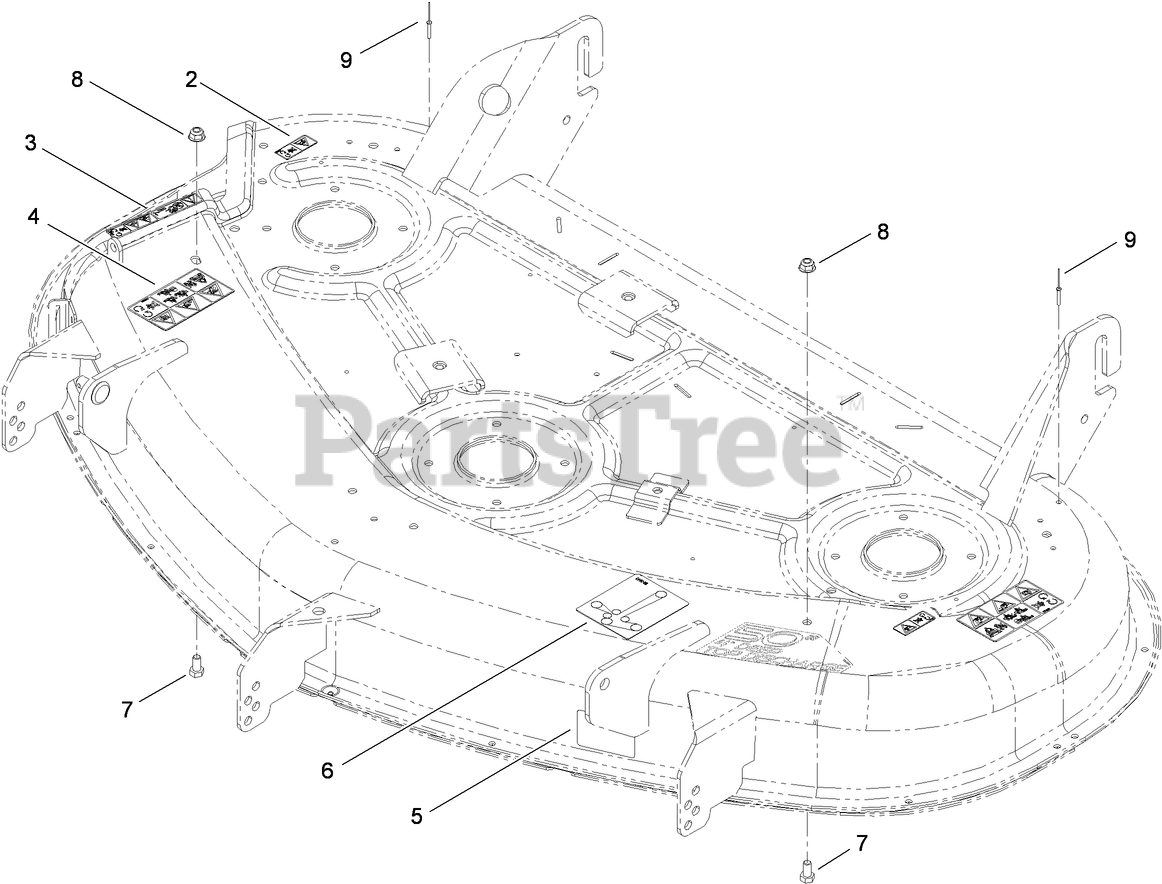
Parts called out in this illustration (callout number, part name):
2	DECAL-DANGER
3	DECAL-DANGER
4	DECAL-DANGER
5	DECAL-SCALP, ANTI
6	DECAL-ROUTING, BELT
7	SCREW-HH
8	NUT-HF, NI
9	RIVET-BLIND
